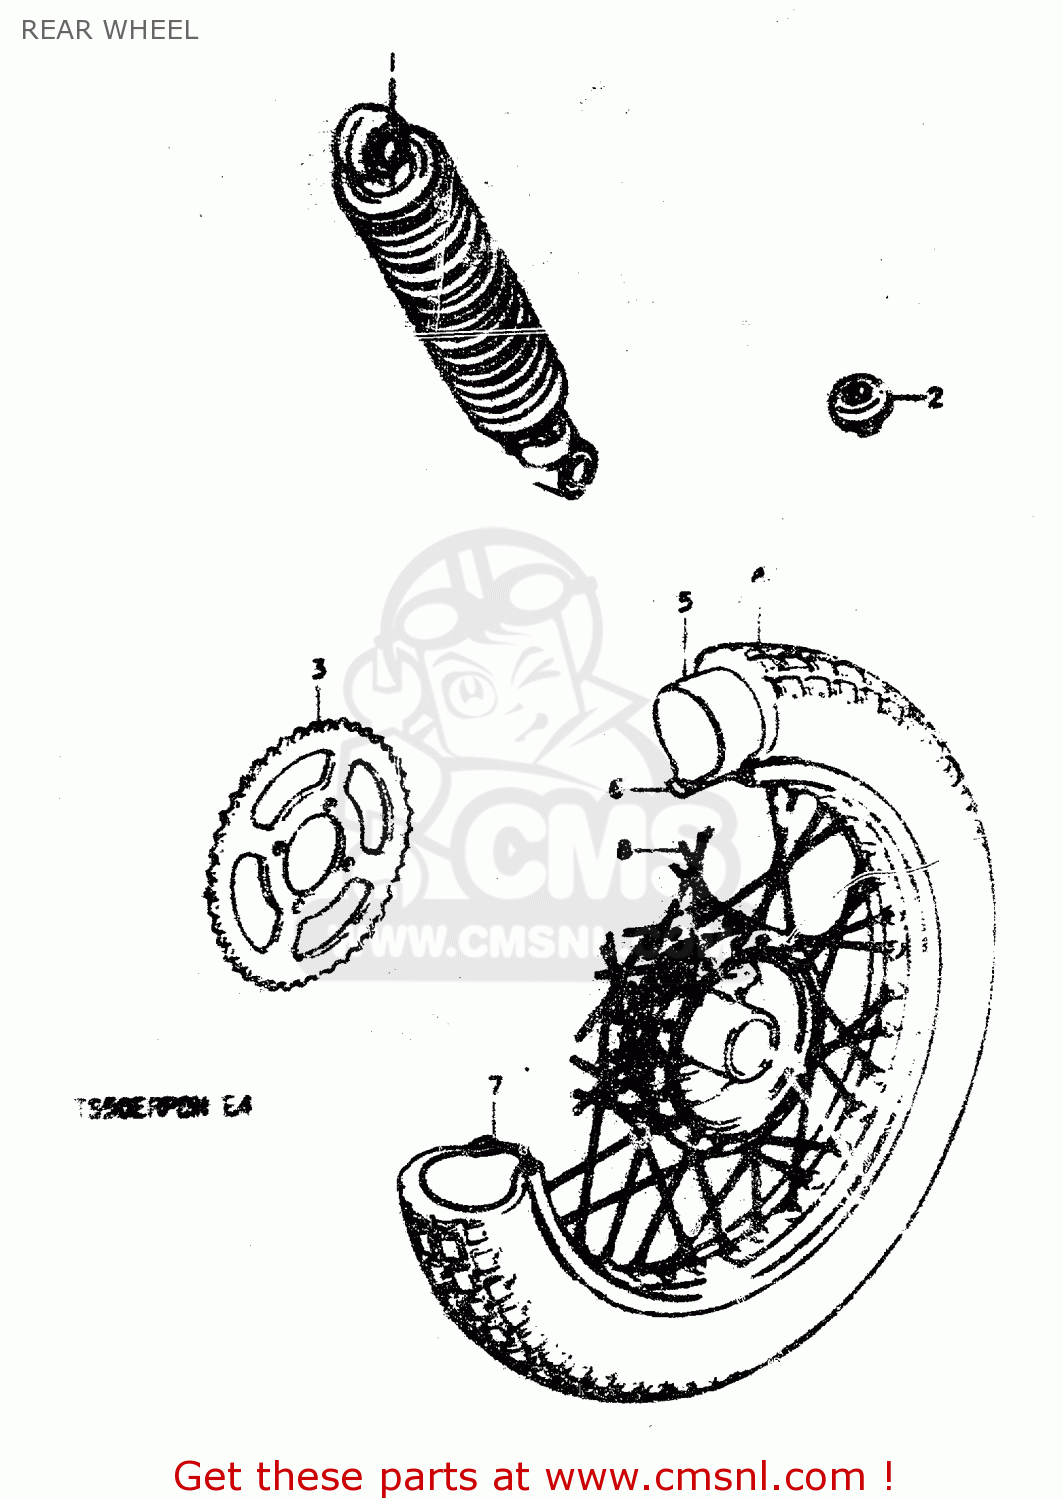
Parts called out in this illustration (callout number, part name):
1	SHOCK ABSORBER ASSY, REAR
2	CUSHION
3	SPROCKET, REAR (NT:49)
4	TIRE
5	TUBE,INNER
6	PROTECTOR,INNER TUBE
7	RIM, WHEEL
8	SPOKE SET
